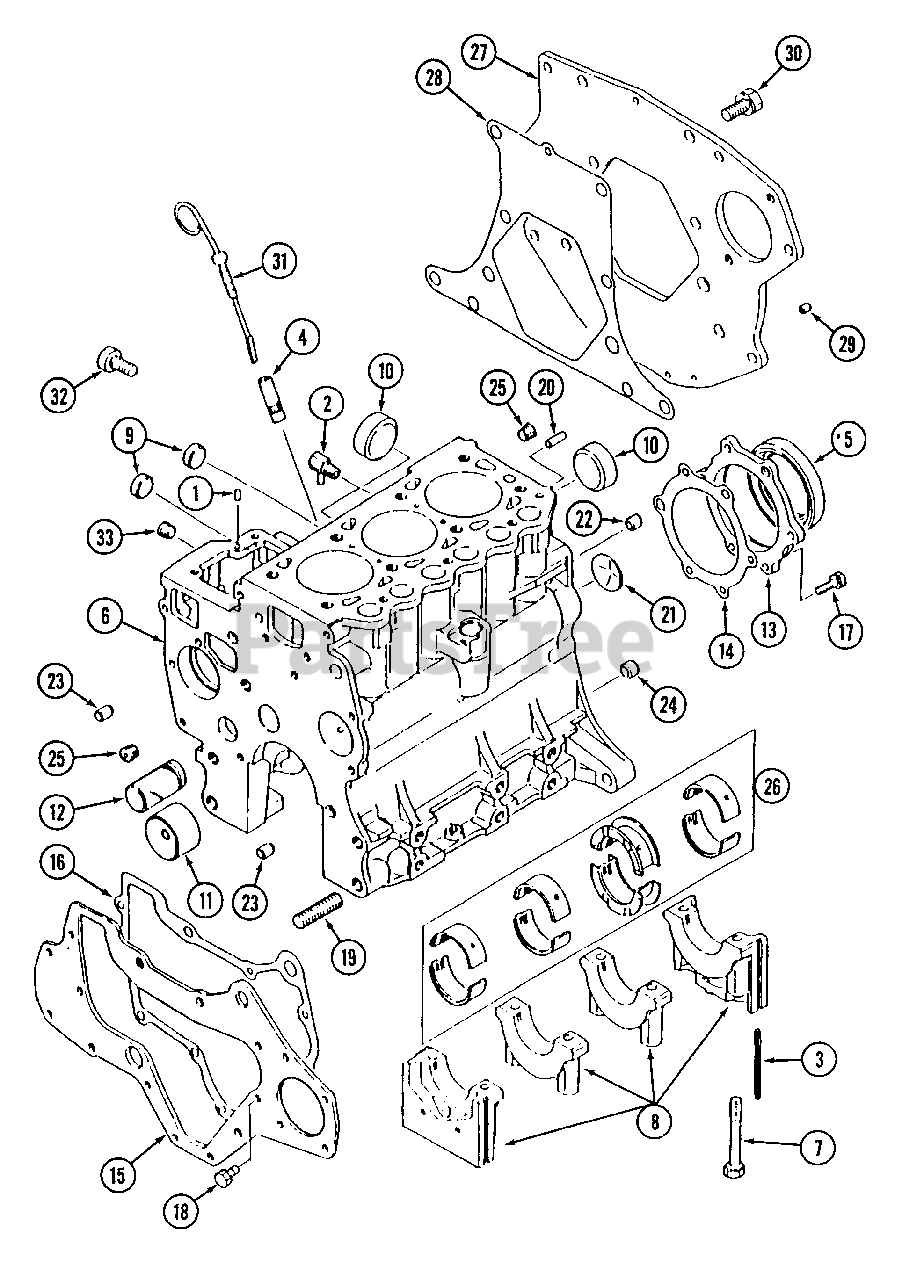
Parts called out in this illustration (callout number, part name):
2	Joint, Water Drain
4	Guide, Oil Level Gauge
6	Cylinder, Block, Sub Assembly
7	Bolt, Bearing Cap
8	Bearing, Cap Ass'y.
9	Cap, Sealing
10	Cap, Sealing
11	Bushing, Camshaft
12	Shaft, Idler
13	Case, Oil Seal
14	Gasket, Oil Seal
15	Plate, Front
16	Gasket, Front Plate
21	Plug, Expansion
22	Bushing, Knock
23	Bushing, Knock
24	Bushing, Knock
25	Plug, Taper
26	Bearing, Set STD.
26	Bearing, Set 0.25 US
26	Bearing, Set 0.50 US
26	Bearing, Set 0.75 US
28	Gasket, Rear Plate
30	Bolt,
31	Gauge, Oil Level
33	Plug, Taper
